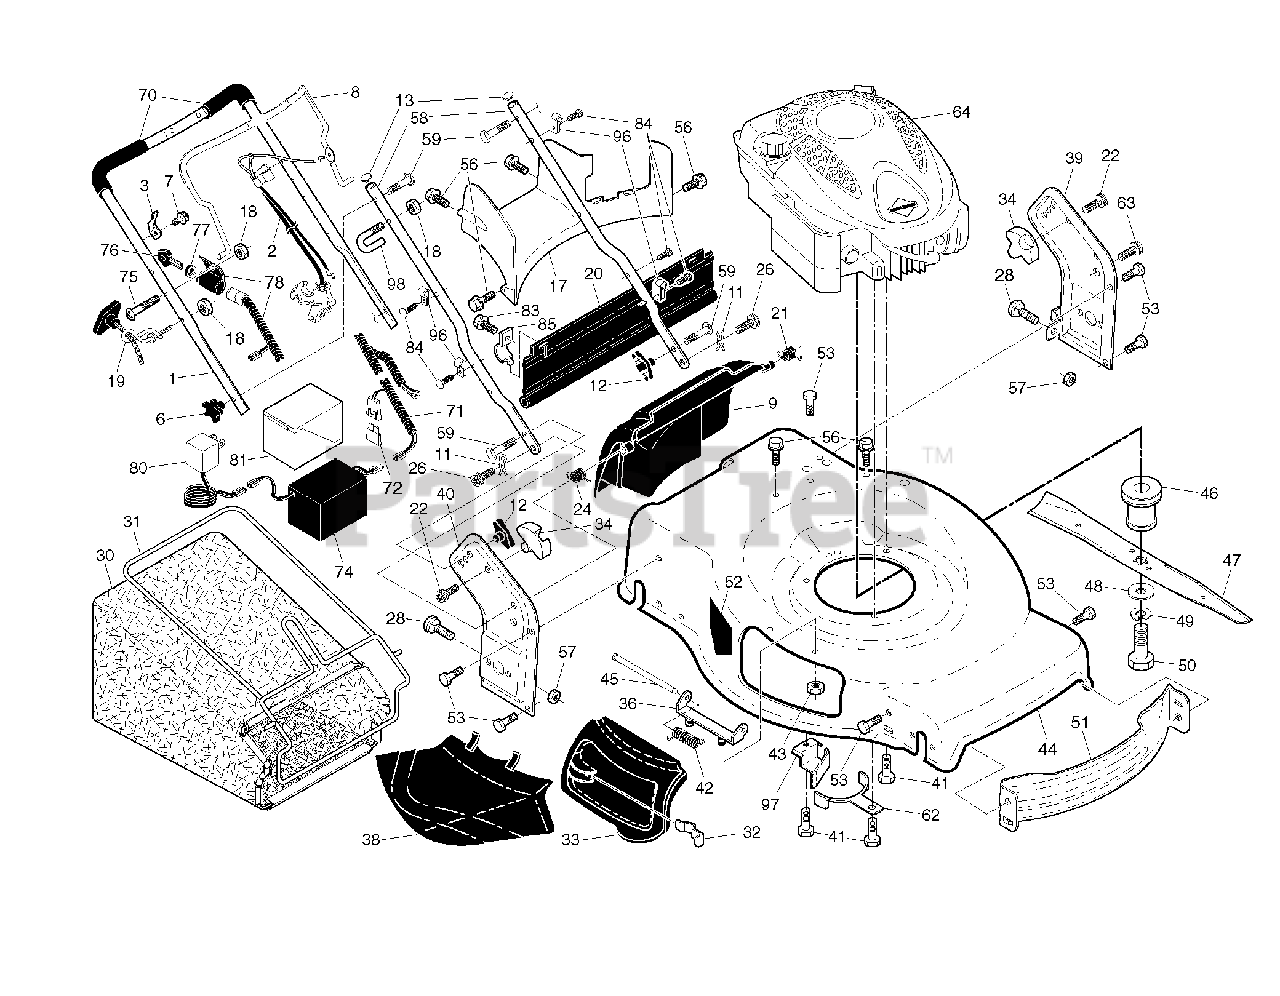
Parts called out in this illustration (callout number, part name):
3	BRACKET.UPSTOP.RT
6	KNOB.HANDLE.PLASTIC.STAR.BLACK
11	COTTER.HAIRPIN.DOOR/HANDLE.PIV
12	KNOB, DEFLECTOR
13	PLUG.PLASTIC.7/8".14-20.GAUGE
17	BAFFLE.REAR.22+.RGD.PL
18	NUT
19	GUIDE.ROPE.STD.BLK.ZIN
20	SKIRT.REAR.22PLUS.RGD/FGD.NEW
21	SPRING.LH.GRAY
22	SCREW.PAN.HEAD.#10
24	SPRING.RH.GRAY
26	SCREW,DOOR/HANDLE.PIVOT
28	BOLT
31	FRAME.GBAG.22PLUS
32	LATCH.DOOR.ZINC
36	HINGE BRACKET ASSEMBLY
38	DEFLECTOR.CLIPPING.22.BLACK
41	BOLT 3/8-16X1-1/8
42	SPRING.TORSION
43	NUT.HEX.FLANGE.1/4
45	ROD.HINGE.21
46	ADPTER.BLAD.25M.VS.22PLU.STAR
47	BLADE.22PLUS
48	WASHER,HARDEN
49	LOCKWASHER
50	SCREW, HEX HD 3/8-24 X 1-3/8
52	DANGER DECAL
53	BOLT.5/16HEX.WHS.HD
56	SCREW.HX.13X.750
57	NUT.FLANGE.5/16
58	HANDLE.LOWER.22+BT.2PC.GRY
59	BOLT, HANDLE 5/16-18X1.75
62	BRACKET.ENG/BELTKEEPER
70	GRIP.HANDLE.FOAM.WIDE.(1 SIDE)
71	HARNESS.22+BATTERY.RWGD
72	FUSE, 40A
74	BATTERY.12 VOLT.22+ RWGD
75	SCREW.(COMBINATION CONTROL)
76	KEY.MOLDED
77	NUT.CAP.SNAP-ON.KEY START
78	HOUSING.WIRING.HARNESS
80	CHARGER.12V.0.1A
83	TAPPING SCREW
84	FASTENER.PUSH.O.250X0.783
85	BRACKET.SKIRT.22+.BZP
96	CLIP.CABLE.BLK
97	BRACKE.BELT.GUIDE.22+
98	CLIP.WIREFORM.PACK.TOR
